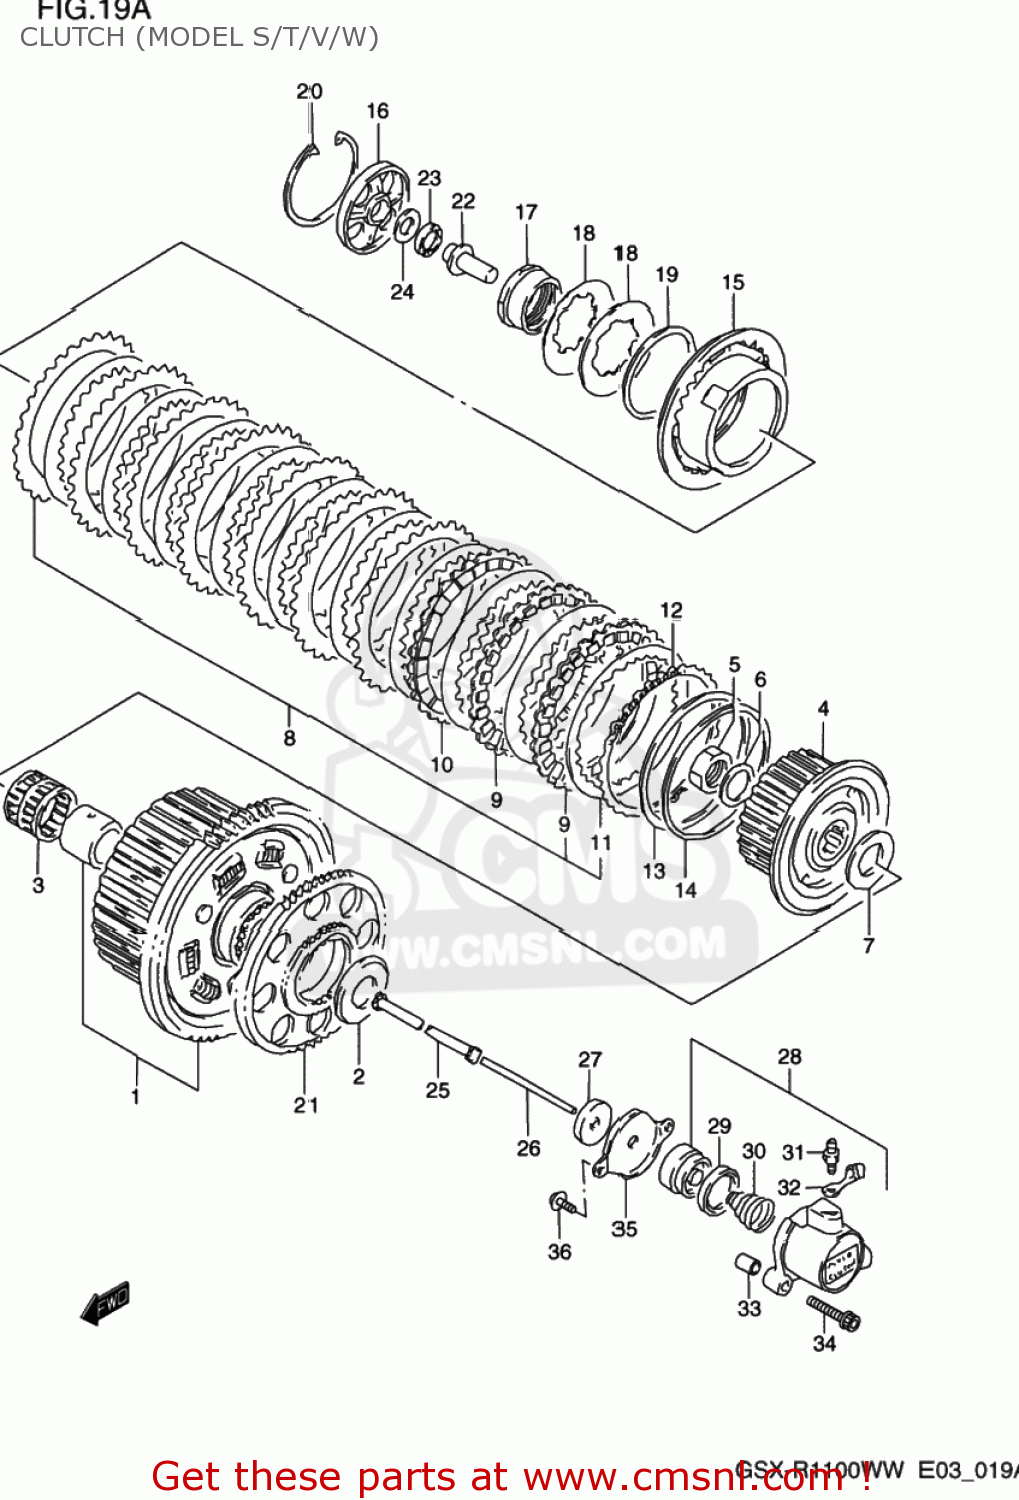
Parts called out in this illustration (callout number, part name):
1	GEAR SET,PRIMARY DRIVE
2	WASHER(25X54X2.5)
3	BEARING(35X40X35.8)
4	HUB,CLUTCH SLEEVE
5	NUT
6	WASHER
7	WASHER(25X50X2.5)
8	PLATE ASSY,CLUTCH
9	PLATE,CLUTCH DRIVE NO.2 (NAS)
10	PLATE,CLUTCH DRIVE NO.1 (NAS)
11	PLATE,CLUTCH DRIVEN (NAS)
12	PLATE,CLUTCH DRIVE NO.2
13	WASHER
14	SEAT,CL SLEEVE HUB WAVE WASHER
15	DISC,CLUTCH PRESSURE
16	LIFTER,CLUTCH PRESSURE DISC
17	HOLDER,CLUTCH SPRING
18	WASHER
19	SEAT,CLUTCH SPRING
20	CIRCLIP
21	GEAR,GENERATOR DRIVE
22	PIECE,CLUTCH PUSH
23	BEARING(15X28X2)
24	WASHER(15.5X28X1)
25	ROD,CLUTCH
26	ROD,CLUTCH PUSH,L
27	SEAL,OIL(6X34X5.5)
28	CYLINDER,CLUTCH RELEASE
29	CUP
30	SPRING,CLUTCH CYLINDER
31	BLEEDER
32	CAP,BLEEDER
33	PIN
34	BOLT,CL.COVER
35	COVER,CLUTCH RELEASE CYLINDER
36	SCREW
